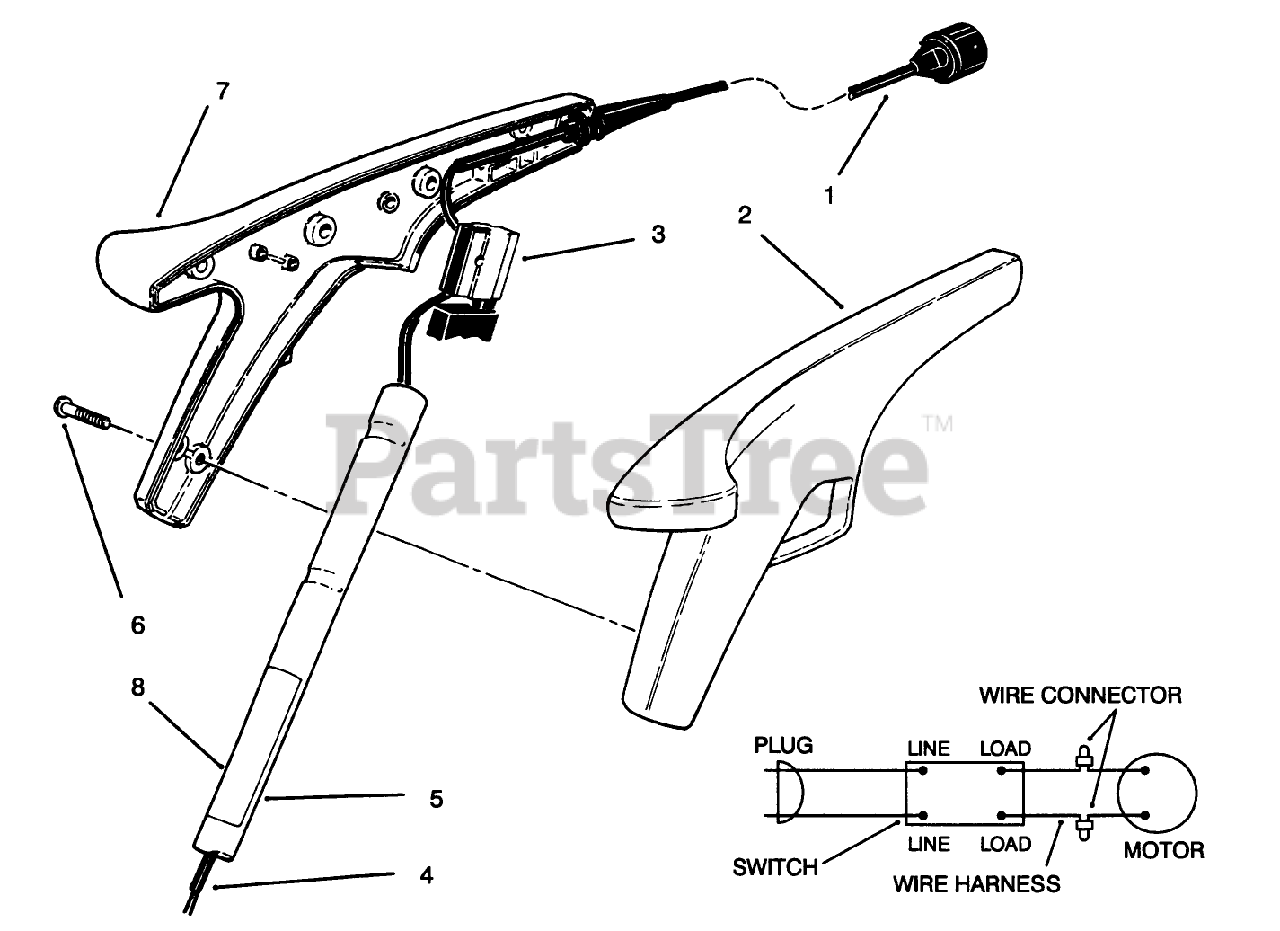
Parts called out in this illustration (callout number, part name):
1	CORD-SUPPLY
2	HAND GRIP - L.H. 8"
3	SWITCH SINGLE SPEED
4	WIRE HARNESS
5	Tube Assy. (Incl. Ref.# 8) Screw
6	Screw
7	HAND GRIP - R.H. 8"
8	Decal-Safety
